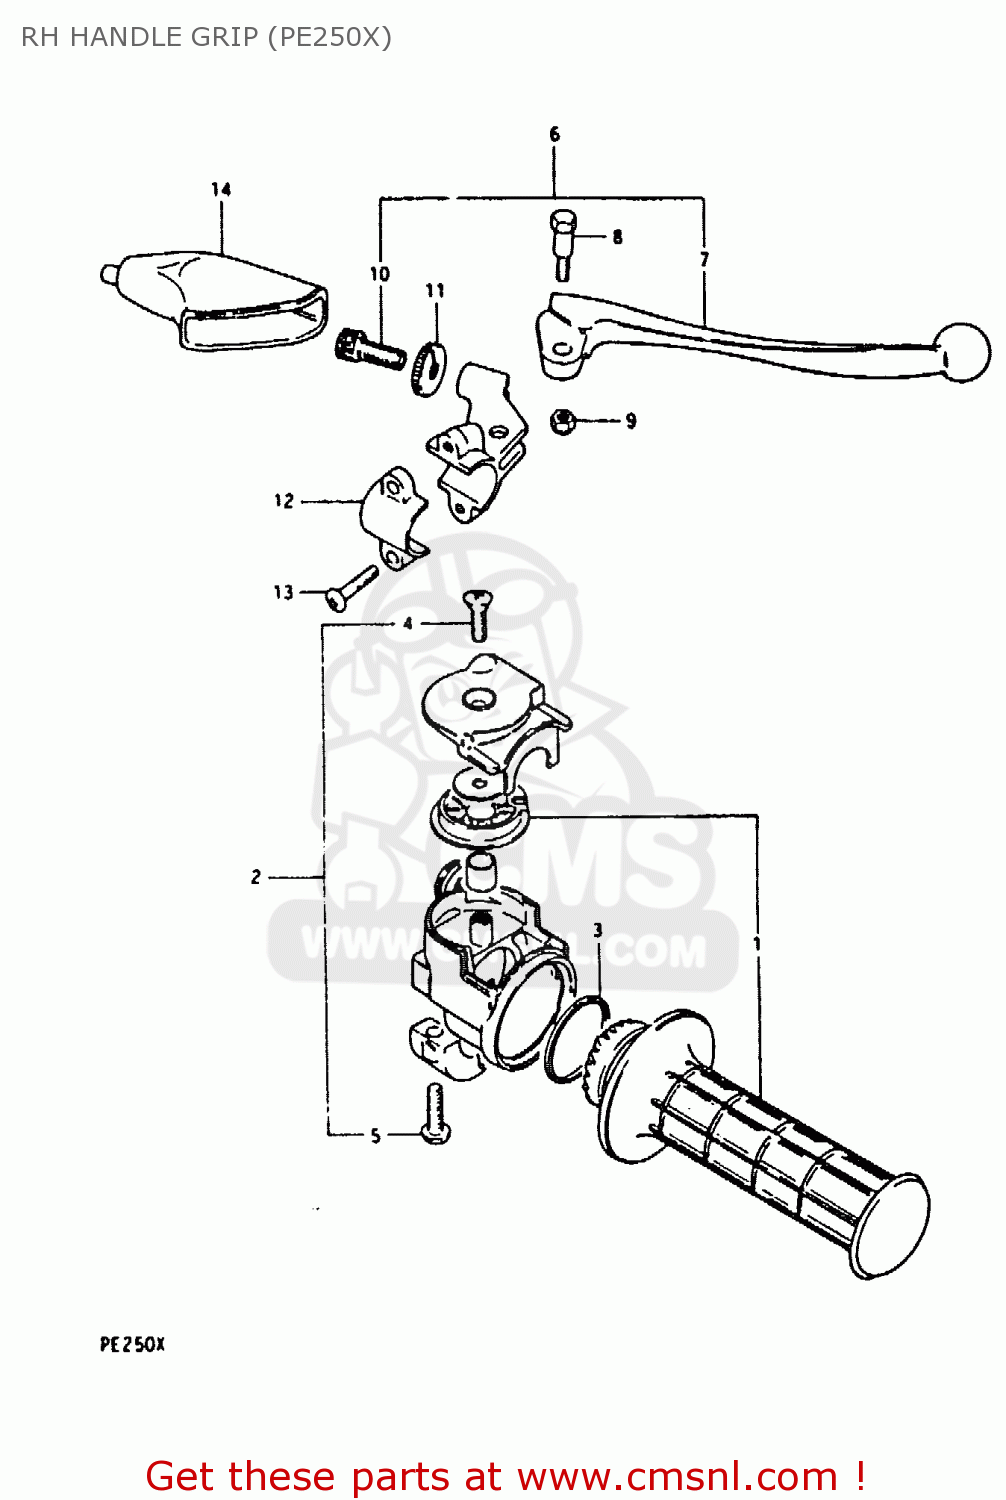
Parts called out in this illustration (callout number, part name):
1	GRIP SET,THROTTLE
2	CASE ASSY,THROTTLE
3	V-RING,THROTTLE GRIP
4	SCREW
5	SCREW 5X20
6	LEVER ASSEMBLY,BRAKE
7	LEVER,BRAKE
8	BOLT,LEVER
9	NUT 6MM
10	ADJUSTER,CABLE
11	NUT,CABLE ADJUSTER
12	BRACKET,LEVER
13	SCREW
14	COVER,CLUTCH LEVER
